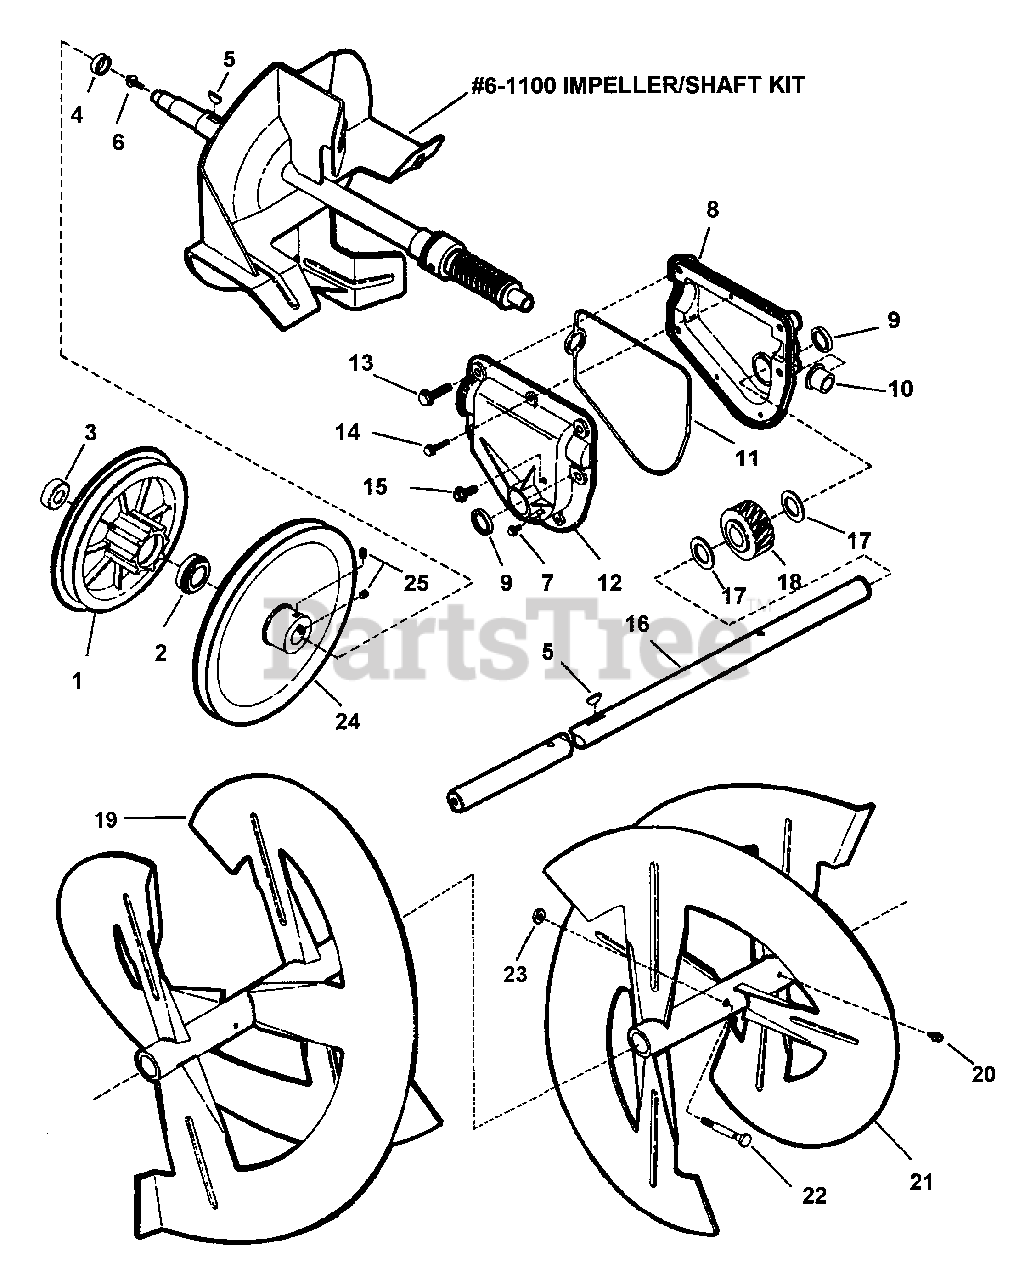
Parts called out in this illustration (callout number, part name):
1	ASSEMBLY, Drive Plate
2	BEARING, Ball
3	BEARING, Ball
5	KEY, #9 (3/16 x 3/4") Woodruff
6	SCREW, 1/4-20 x 1/2" Truss Head Self-Tapping (Torx)
7	SCREW, #10-24 x 1/2" Hex Washer Self-Tap (Torx)
8	COVER, Gear Case (Left Hand)
10	BUSHING
11	"O" RING
12	COVER, Gear Case (Right Hand)
13	SCREW, 1/4-20 x 3/4" Hex Washer Self-Tapping
14	SCREW, #10-24 x 5/8" Hex Washer Self-Tap, Grade 5
15	SCREW, 1/4-20 x 3/8" Hex Washer Self-Tapping
16	SHAFT, Auger
17	WASHER, Thrust
18	GEAR, Worm
19	AUGER, (Left Hand)
20	LUBE FITTING, Straight (press-fit for .187 dia. Hole)
21	AUGER, (Right Hand)
22	PIN, Shear, .248 ID. X 1.75 LG
23	COTTER PIN, .094 X 0.750 BLK
24	PULLEY, 8.36" O.D.
25	SCREW, 5/16-18 x 5/16 Hex Socket Set
61100	KIT, Impeller/Shaft Weldment Replacement
